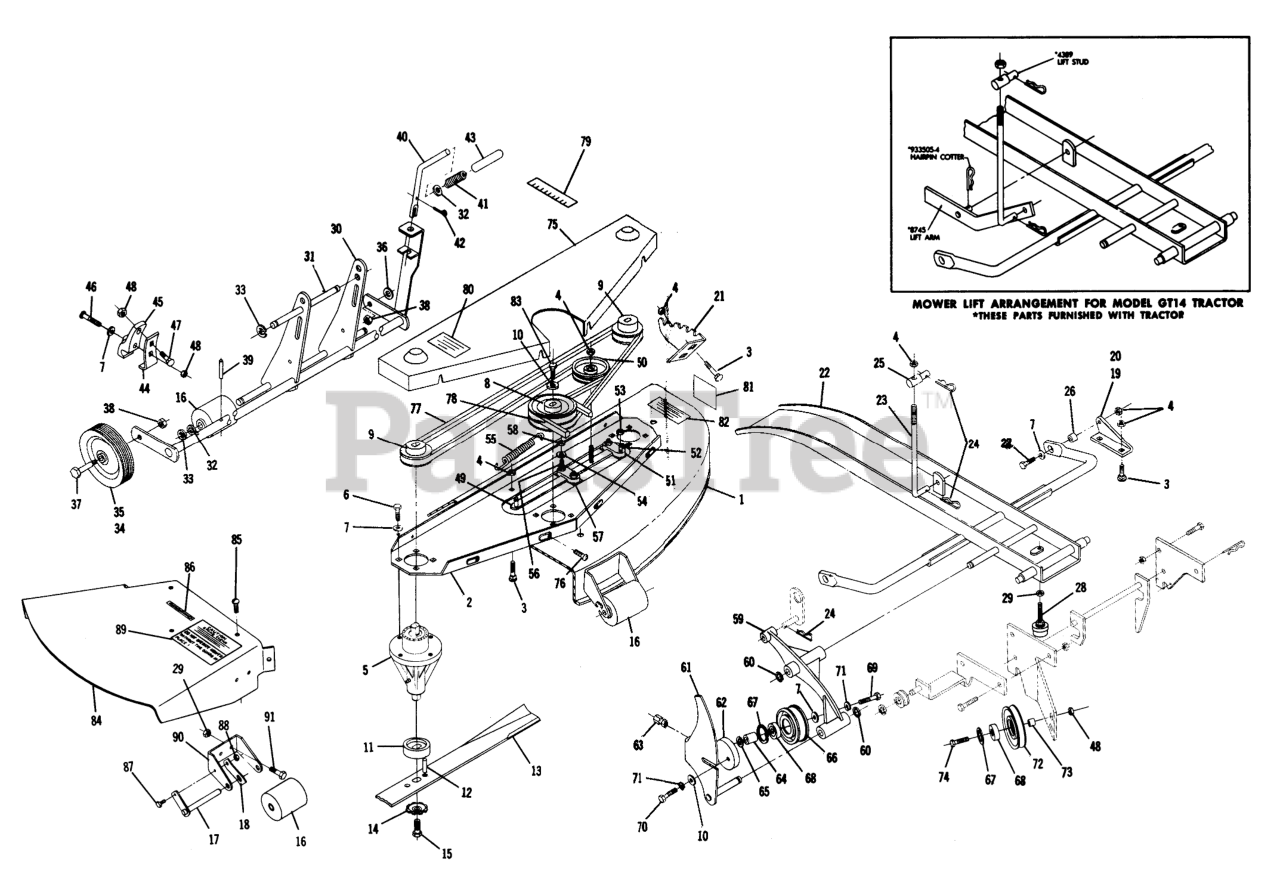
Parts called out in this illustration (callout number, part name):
1	Deck
2	Support
3	Bolt-3/8-16 x 3/4
4	3/8-16 E.S.
5	Ass-y-Sealed Spindle Bearing
6	Bolt 3/8-16 x 7/8
7	Washer
8	Pulley-Center
9	Pulley-Right & Left
10	WASHER
11	Cup-Spindle
12	SPIROL ROLL PIN
13	BLADE KIT 48 LF
14	WASHER
15	Bolt 3/8-16 x 7/8
16	Roller
17	Roller Shaft
18	SPRING ROLLER STOP
19	Bracket-Deck R.H.
20	Bracket-Deck L.H.
21	Quadrant
22	Ass-y Support-Mower
23	ROD LIFT
24	Hairpin
25	TRUNNION-LIFT
26	SPACER
27	Bolt 3/8-16 x 1
28	LEVELER MOWER
29	Nut, 5/16-18
30	Ass-y.-Gage Wheel Support
31	Pin
32	Washer
33	E Ring
34	Wheel
35	BEARING
36	Washer-Spacer
37	BOLT-SHOULDER
38	3/8-16 Jam Nut
39	Roll Pin
40	FORK
41	Spring
42	Hairpin
43	GRIP
44	Clip-Axle
45	SUPPORT AXLE
46	Bolt 3/8-16 x 1 5/8
47	Bolt Carriage 3/8-16 x 1
49	ASSY BAR IDLER SUPPO
50	Pulley-Idler
51	Side Block
52	Bolt-5/16-18 x 1/4
53	Nut 5/16-18
54	Washer
55	SPRING R
56	Bolt-5/16-18 x 1 1/2
57	SLIDE
58	Nut-Nylok
59	ARM PIVOT R
60	RING LAM L 262
61	ASSEMBLY CAM LEVE R
62	Ass-y Idle Support
63	Nut
64	SPACER
65	Lockwasher-3/8 Int.Tooth
66	PULLEY IDLER
67	INTERNAL SNAPRING
68	BEARING
69	Bolt Hex 3/8-16
70	Bolt 3/8-16 x 1
71	Lockwasher
72	PULLEY IDLER
73	SPACER
74	Bolt, 3/8-16 x 1/2
75	Cover
76	Bolt 1/4-20 x 3/8
77	V-BELT
78	V BELT
79	Decal-Height Adj.
80	Decal Belt Installation
81	DECAL-WHEEL HORSE
82	Decal
83	Bolt 3/8-16 x 3/4 Hex
84	Chute Extension
85	Bolt 5/16-18 x 5/8
86	Decal Mower Width
87	Bolt-1/4-20 x 5/8
88	Nut-Nylok
89	Decal-Warning
90	Bracket
91	Bolt Hex 5/16-18
92	Bolt-1/4-20 x 5/8
93	Nut 1/4-20
